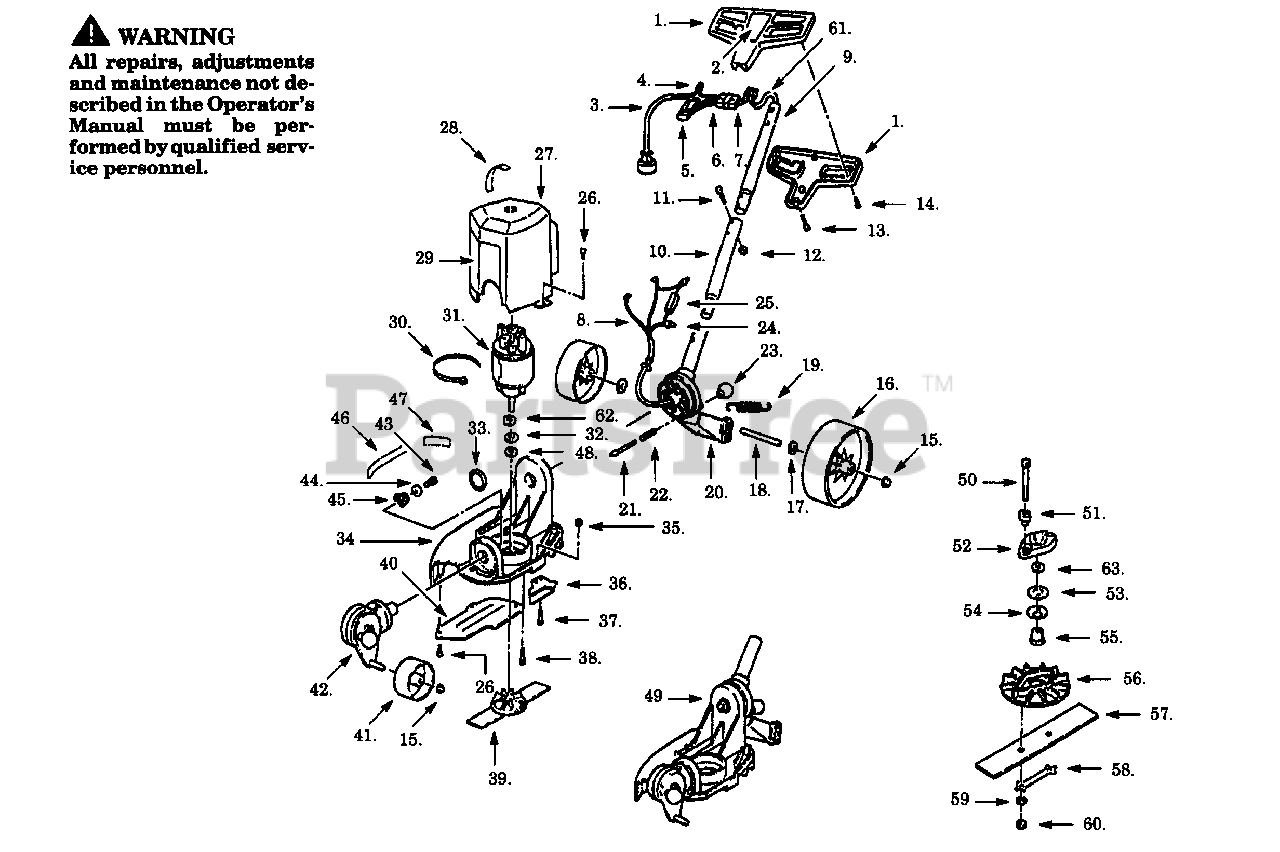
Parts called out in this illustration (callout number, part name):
1	Handle Set
2	Handle Label Model 1250
2	Handle Label Model 9125 (Not a serviceable part)
3	Power Cord
4	Wire Nut
6	Bridge Ass'y.
7	Insulator Shield
8	Harness Ass'y.
9	Upper Tube Model 1250
9	Upper Tube Model 9125
10	Lower Tube Model 1250
10	Lower Tube Model 9125
12	Locknut Model 1250
12	Locknut Model 9125
15	Push Nut
16	Rear Wheel
18	Rear Axle
20	Rear Swivel
21	Swivel Lock Shaft
22	Swivel Lock Spring
24	Terminal Cap
25	Resister
27	Motor Cover
28	Rear Adjust Label (Not a serviceable part)
29	Motor Cover Label Model 1250
29	Motor Cover Label Model 9125 (Not a serviceable part)
30	Tie Wrap
31	Motor Ass'y.
33	Retaining Ring
34	Deck Frame
36	Blade Guide
39	Blade Ass'y.
40	Side Guard Plate
41	Front Wheel
42	Front Swivel Ass'y.
45	Front Swivel Spring
46	Dyn Brake Label (Not a serviceable part)
47	Warning Label Model 1250 (Not a serviceable part)
47	Warning Label Model 9125
49	Edger Frame Ass'y.
51	Insulating Sleeve
52	Clutch Plate Model 1250
52	Clutch Plate Model 9125
54	Spring Washer
55	Clutch Sleeve
58	Lock Strap
59	Lockwasher
61	Harness Ass'y.
62	Retaining Ring
